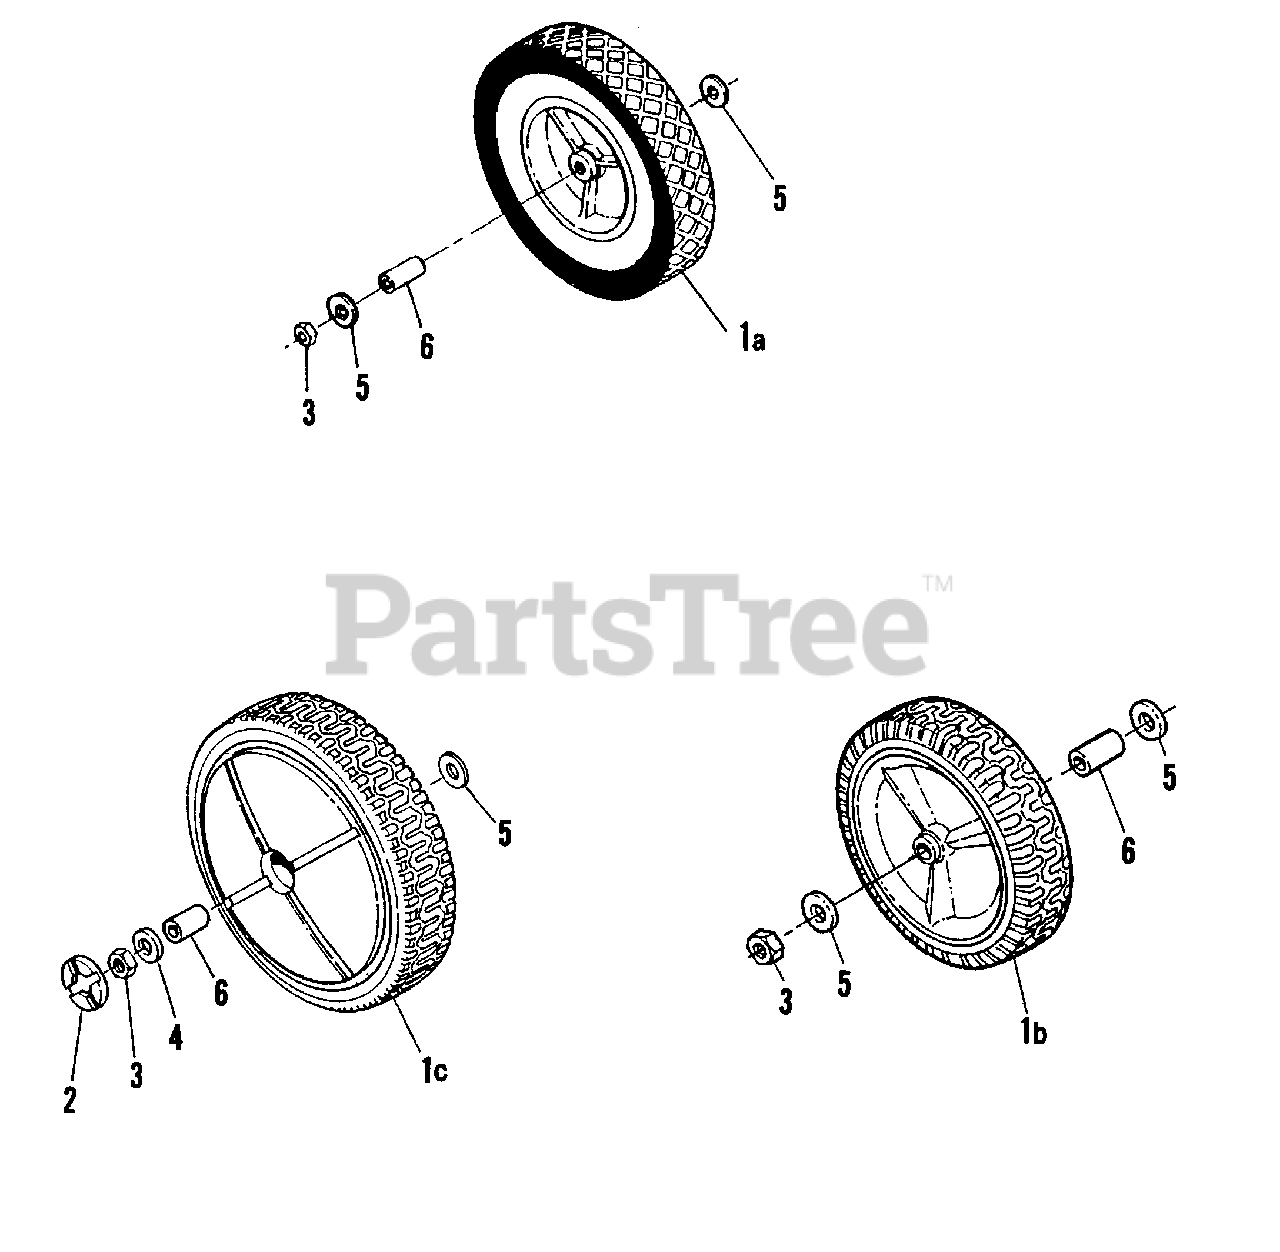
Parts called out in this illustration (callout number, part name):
1A	WHEEL, 7 x 1.50 - Plastic
1B	WHEEL, 7 x 1.75 - Plastic
1C	WHEEL, 7 x 1.75 - Plastic
2	PLUG, Wheel
3	NUT, 7/16 - 20 Hex Thin
4	WASHER, 7/16" ID SAE
5	WASHER, 1" O.D. Flat
6	AXLE BUSHING
